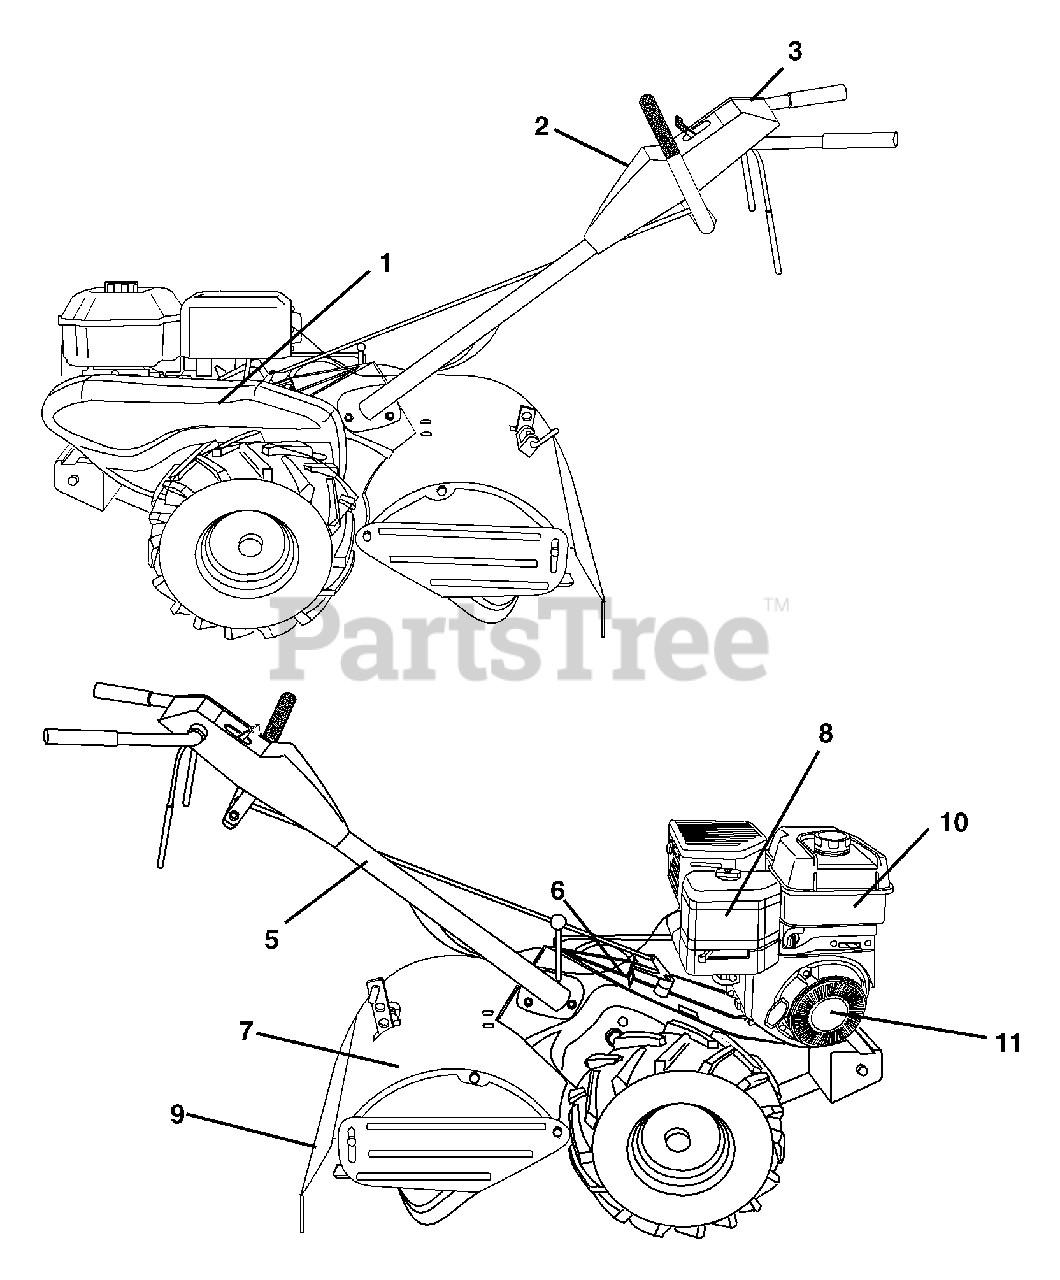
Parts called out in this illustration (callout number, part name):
1	Decal, Blt Grd
2	Decal, CNTRL PNL
3	Decal, Control Tine
5	Decal, Hand Placement
6	Decal, Shift Indicator
7	Decal, Warning
8	Decal, Engine B&S 6.5 HP
9	Decal, Warning, Rotating Tines
10	Decal, Engine Intek REF
11	Decal, Rewind Intek #274350
